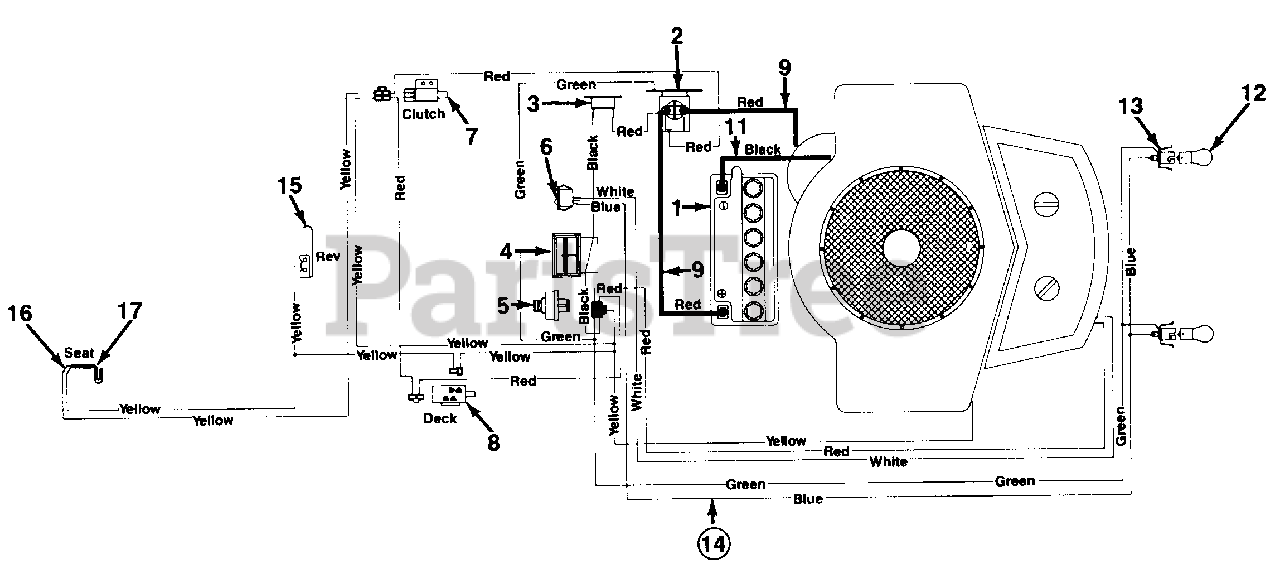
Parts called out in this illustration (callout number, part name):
1	N Battery
2	N Solenoid
3	Circuit Breaker
4	Ammeter
5	Ignition Switch
6	Light Switch
7	N Safety Switch
8	N Safety Switch
9	Electric Wire 14" Lg.
11	Ground Wire 7.5" Lg.
12	Lamp
13	Socket
14	N Wire Harness
15	Spring Switch
16	Spring Switch
17	N Spring Switch
